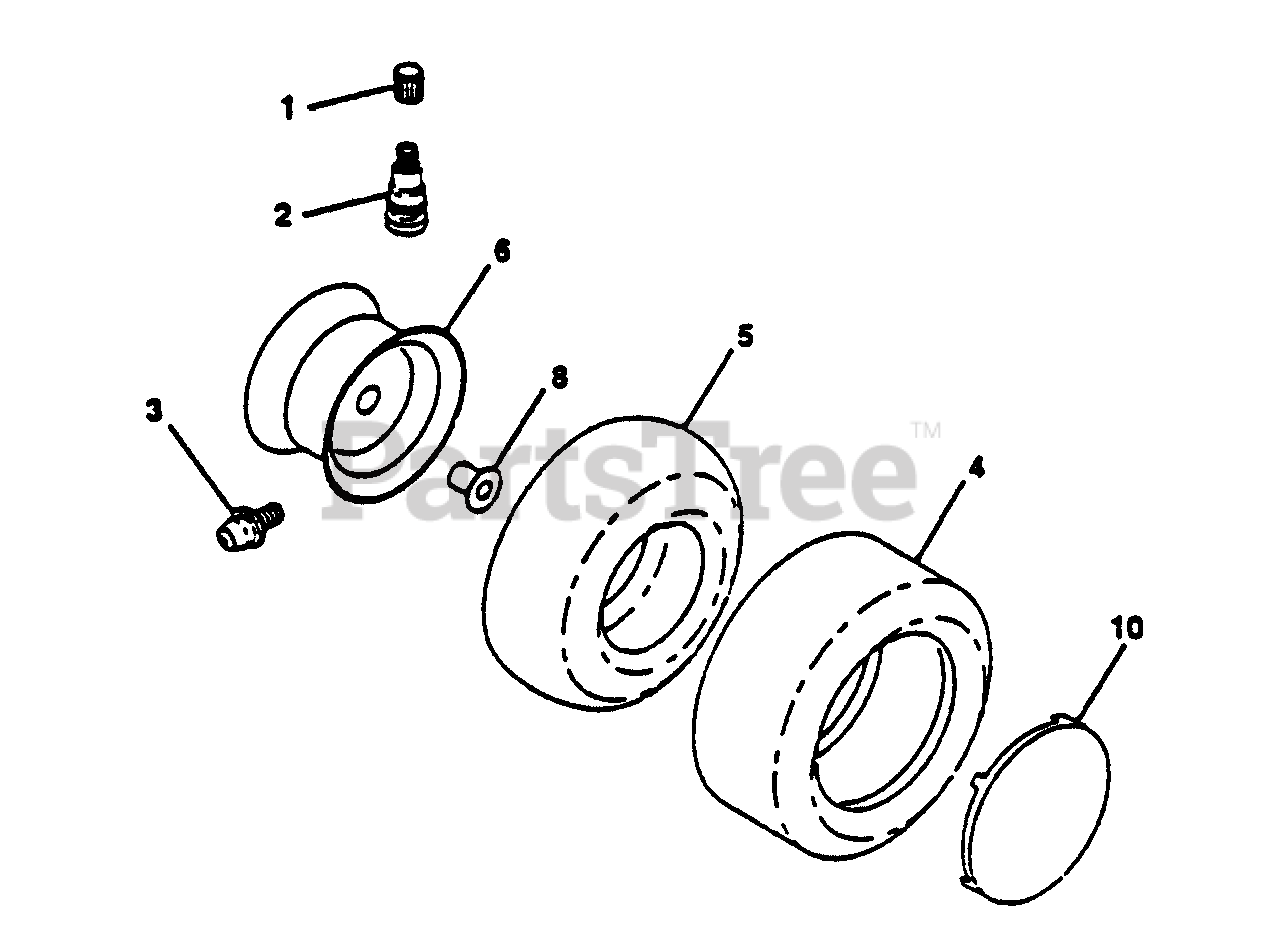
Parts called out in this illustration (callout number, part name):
1	Cap Valve Tire
2	Stem Valve
3	Fitting Grease
4	Tire F Ts 15 X 6 0 - 6 Service
4	Tire R Ts 20 8-8 C Service
5	Tube Front
5	Tube Rear
6	Rim Asm 8' rear White Service
6	Rim Asm 6' front White Service
8	Bearing Flange
10	Cover Wheel 6" white
10	Cover Wheel 8" white
